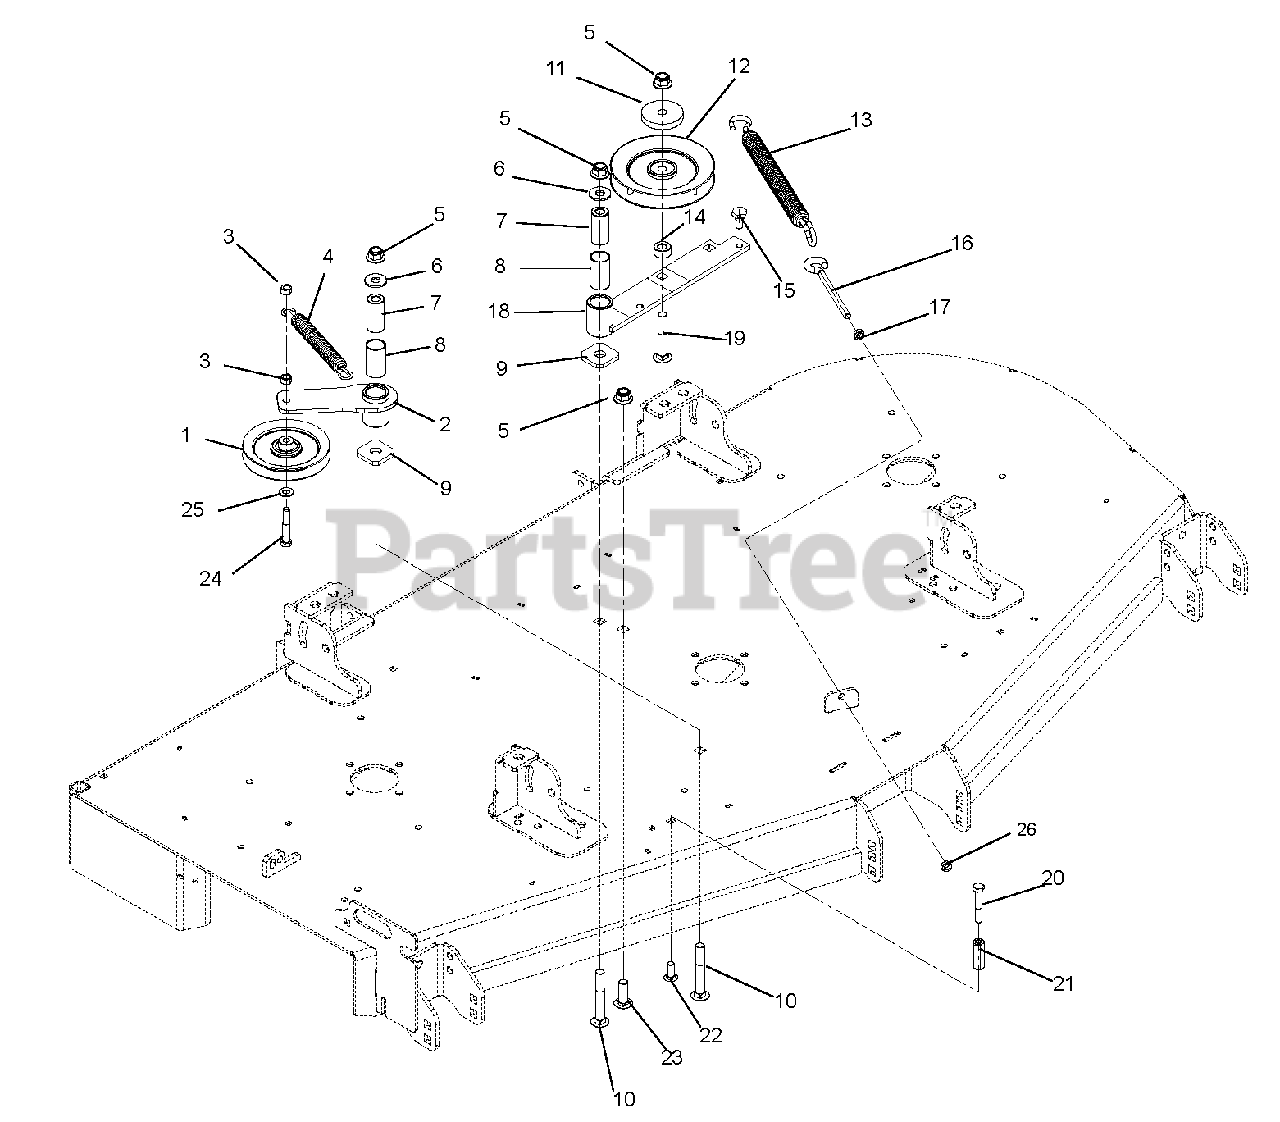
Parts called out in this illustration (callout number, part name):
1	Sheave, .38"ID x 5.00"OD V-Idler
2	Weldment, Idler Arm
3	Nut-Locking-Center .38-16
4	Spring, Extension
5	Nut-Locking-Nylon-Flange .50-13
6	Washer-Flat-Steel .563 x 1.38 x .109
7	Bushing, Spacer .505/.500 x .999/.996 x 2.05/2.03
8	Bushing, 1.00 x 1.125 x 1.936
9	Washer-Flat .640 x 1.75 x .250
10	Bolt-Round Head Square Neck .50-13 x 3.50 Grade 5
11	Cap, Idler Bearing Sealing
12	Sheave, .50"ID x 6.00"OD V-Idler
13	Spring, Extension
14	Bushing, Spacer .502 x .997 x .50
15	Bolt,Shoulder EP .38-16 x .30 Hex
16	Bolt, .38-16 x 5.50 .62 Diameter Eye
17	Nut-Hex-Jam .375-16
18	Weldment, Idler Arm
19	Bolt-Round Head Square Neck .50-13 x 3.00 Grade 5
20	Bolt-Hex .38-16 x 1.75 Grade 5
21	Nut, Cupling .375-16 x 1.75
22	Bolt-Round Head Square Neck .38-16 x 1.00
23	Bolt-Round Head Square Neck .50-13 x 1.50 FULL Thread Grade 5
24	Bolt-Hex .38-16 x 2.25 Grade 5
25	Washer-Flat-Steel .406 x .812 x .065
26	Nut, Locking-Center-Jam .375-16
